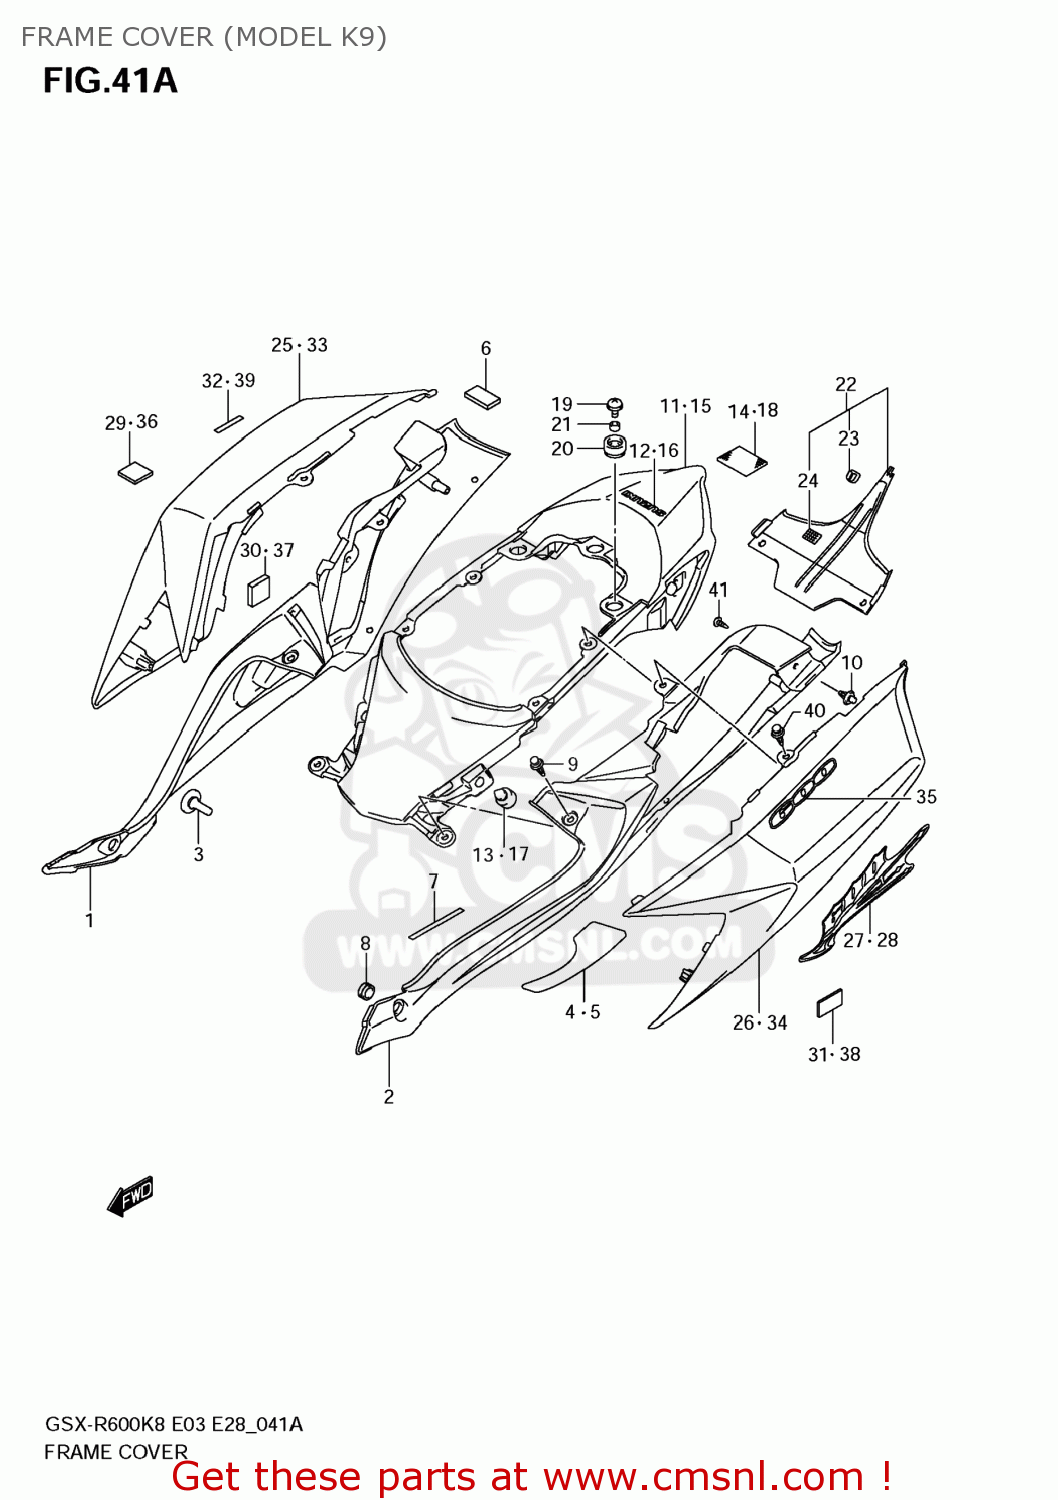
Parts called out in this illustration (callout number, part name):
1	COVER,FRAME,R(BLACK)
2	COVER,FRAME,L(BLACK)
3	CUSHION
4	TAPE,FRAME COVER,R
5	TAPE,FRAME COVER,L
6	CUSHION,FRAME COVER RR LWR
7	TAPE,FRAME COVER FR
8	CUSHION,FRAME COVER FR
9	CLIP
10	CLIP(BLACK)
11	COVER,FRAME CTR
12	EMBLEM,SUZUKI
13	CUSHION(11.5X22X20)
14	FASTENER,RR COMB LAMP
15	COVER,FRAME CTR
16	EMBLEM,SUZUKI
17	CUSHION(11.5X22X20)
18	FASTENER,RR COMB LAMP
19	SCREW(6X16)
20	CUSHION,FRAME COVER RR
21	SPACER(6.5X10X7)
22	COVER,FRAME RR CTR
23	CUSHION,FRAME COVER RR CTR
24	FASTENER,FRAME COVER
25	COVER,FRAME RR,R
26	COVER,FRAME RR,L
27	TAPE,FRAME COVER RR,R
28	TAPE,FRAME COVER RR,L
29	CUSHION,COVER
30	CUSHION,SIDE
31	CUSHION,SEAT TAIL COVER LWR RR
32	TAPE,SEAT TAIL COVER
33	COVER,FRAME RR,R
34	COVER,FRAME RR,L
35	EMBLEM,FRAME COVER
36	CUSHION,COVER
37	CUSHION,SIDE
38	CUSHION,SEAT TAIL COVER LWR RR
39	TAPE,SEAT TAIL COVER
40	CLIP
41	SCREW
